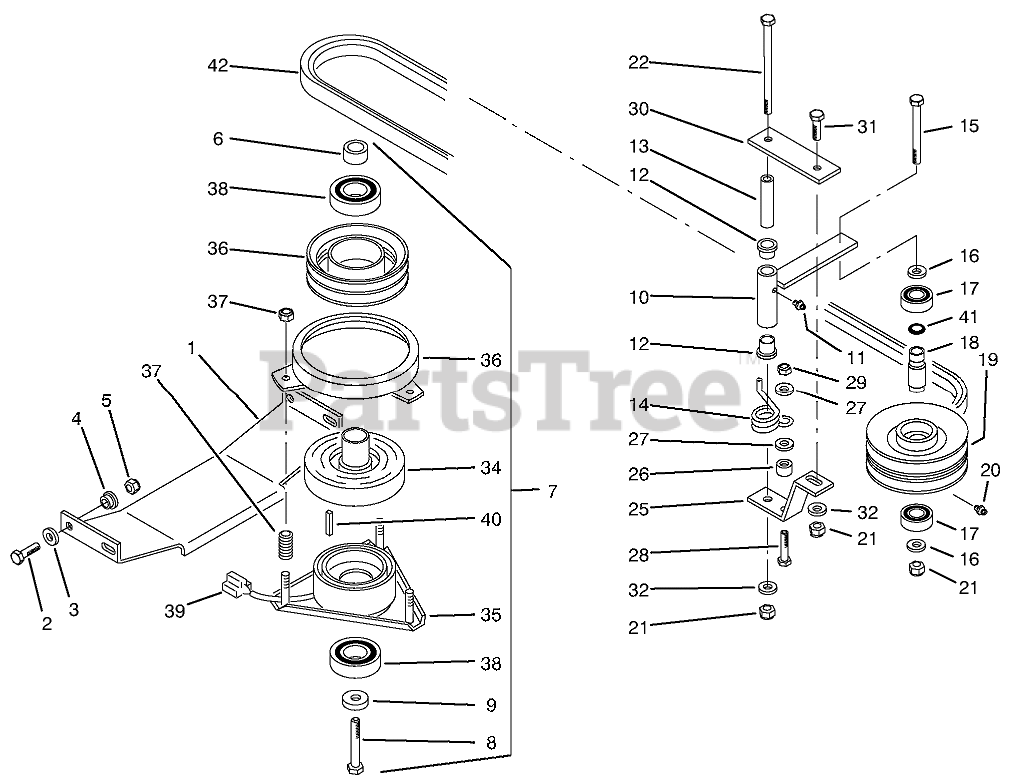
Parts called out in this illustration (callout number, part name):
1	BRACKET CLUTCH ST R
2	SCREW-HH
3	WASHER-PLAIN
4	BUSHING
5	NUT-LOCK, NI
6	SPACER
7	Electric Clutch Assembly (Incl. Ref. #6, 8, 9 & 34-40)
8	SCREW-HH
9	WASHER
10	Arm-Idler
11	Fitting-Grease
12	BUSHING
13	SPACER
14	SPRING-TORSION
15	SCREW-HH
16	Washer
17	BEARING-BALL
18	SPACER-PTO IDLER
19	PULLEY 2- GROOVE
20	FITTING-GREASE
21	NUT-LOCK, NI
22	SCREW-HH
25	Bracket-Idler
26	Spacer
27	WASHER-FLAT
28	SCREW-HH
29	NUT-LOCK, NI
30	Plate
31	SCREW-HH
32	WASHER-FLAT
34	ROTOR ASSEMBLY
35	Field Assembly (Incl. Ref. #38)
36	Armature & Pulley Assembly (Incl. Ref. #38)
37	ACCESS SPRING & NUT
38	BEARING-ELEC CLUTCH
39	CONNECTOR BODY B
41	O RING
42	V-BELT
